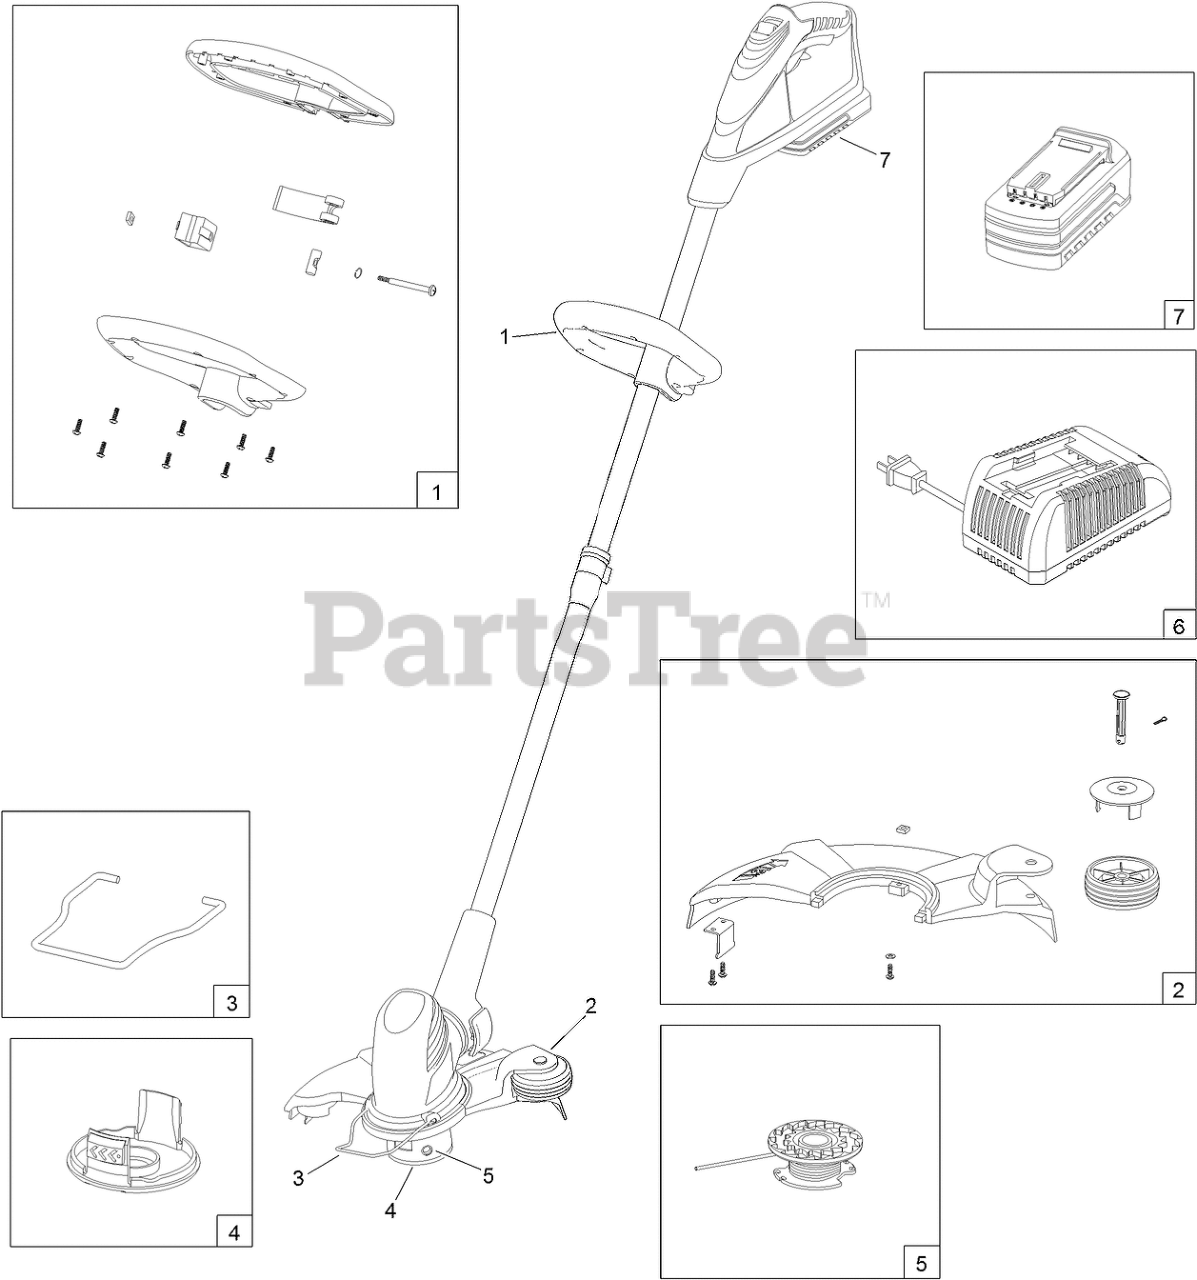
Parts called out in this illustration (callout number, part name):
1	ASSIST HANDLE ASM
2	SHIELD ASM
3	CLIP-GUIDE, EDGER
4	CAP-RETAINER, SPOOL
5	SPOOL-REPLACEMENT
6	CHARGER-20V MAX, LI ION
7	BATTERY-LI ION, 20V MAX
